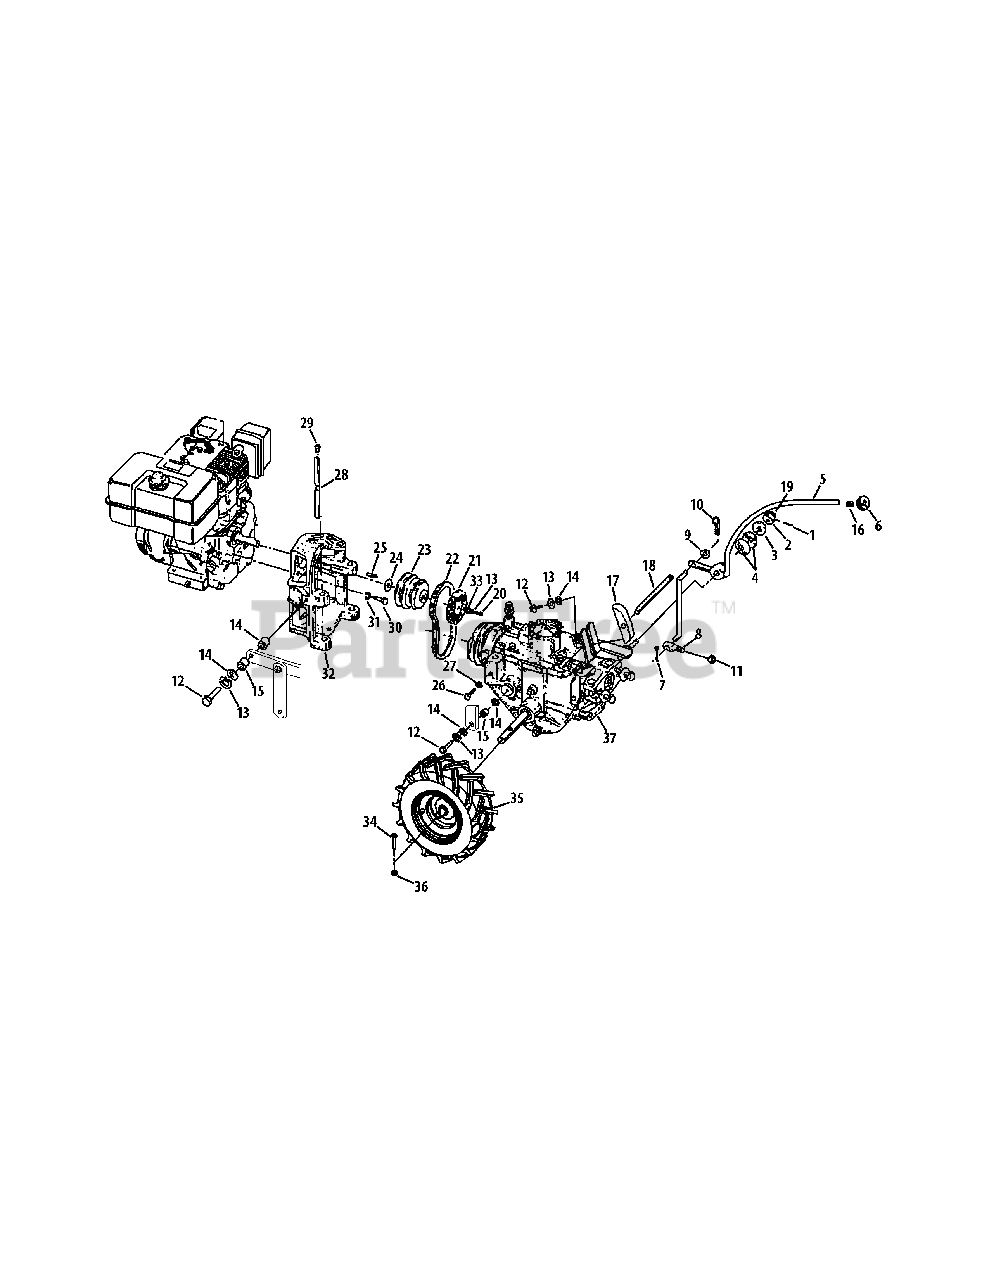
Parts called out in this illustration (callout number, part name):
1	Spring Pin, 1/8"
2	Flat Washer, .510 x 1.0 x .125
3	Shoulder Washer, 1.25 x .50 x .25
4	Disc Spring Washer
5	Wheel Speed Shift Lever
7	Cotter Pin, 3/32" x 1"
9	Flat Washer, .344 x .688 x .065
10	Hair Pin Cotter
11	Hex Locknut, 5/16"-18
12	Hex Head Screw, 3/8"-16 x 1"
13	Lockwasher, 3/8"
14	Flat Washer, .406 x .810 x .051
15	Bushing Spacer, .5 x .375 x .3
16	Retaining Ring
17	Belt Adjustment, 3-7/8"
18	Belt Adjustment Rod
19	Hex Nut, 1/2"-20
20	Hex Head Screw, 3/8"-24 x 1.75
21	Reverse Disc
22	Forward Drive Belt
23	Engine Power Take-off Pulley
24	Flat Washer, .766 x 1.0 x .031
24	Flat Washer, .766 x 1.0 x .062
25	Engine Pulley Key, 3/16"x 2-1/2"
26	Hex Head Screw, 5/16"-18 x 1"
27	Hex Nut, 5/16"-18
28	Engine Mounting Bar
29	Thread Protector Plug
30	Hex Head Screw, 5/16"-24 x 1.125
31	Lockwasher, 5/16"
33	Flat Washer, .406 x 1.0 x .105
34	Hex Screw, 1/4"-20 x 1-1/2"
35	Wheel Assembly, 16 x 4.6 x 8"
36	Hex Flange Nut, 1/4"-20
37	Clutch Bracket
